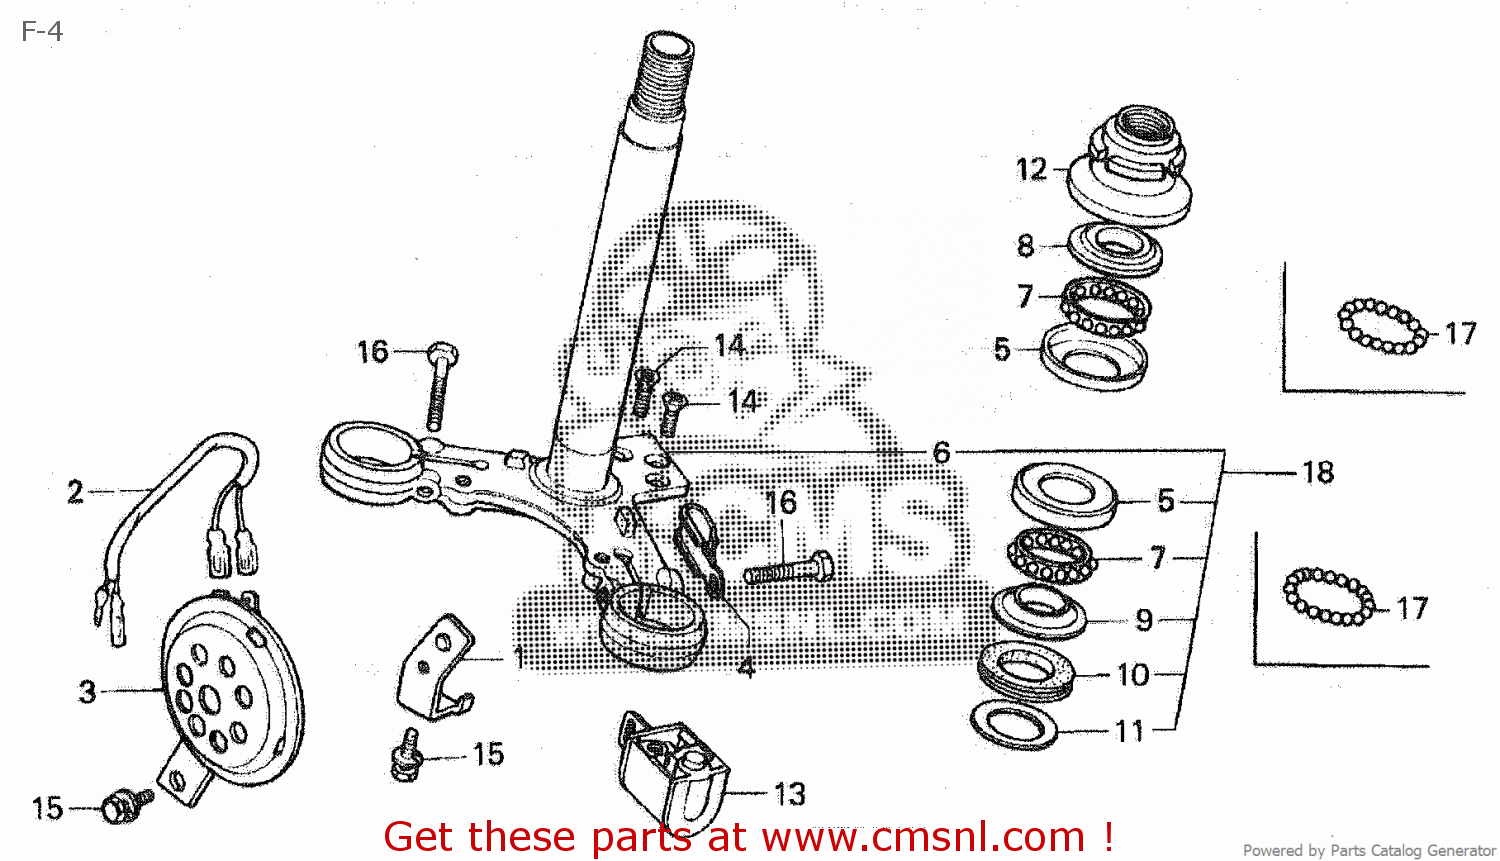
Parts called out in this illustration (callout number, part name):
1	STAY,HORN
2	SUB CORD,HORN
3	HORN COMP(HIGH)
4	CLIP, WIRE
5	RACE,STRG.BALL
6	STEM COMP.,*NH-1*
7	BALL ASSY.,STEERI
8	RACE,STRG.TOP CON
9	RACE STRG.BOTTOM
10	DUST-SEAL
11	WASHER, DUSTSEAL
12	THREAD
13	LOCK,STRG.HANDLE
14	SCREW, CROSS 6X12
16	BOLT,HEX.,8X32
